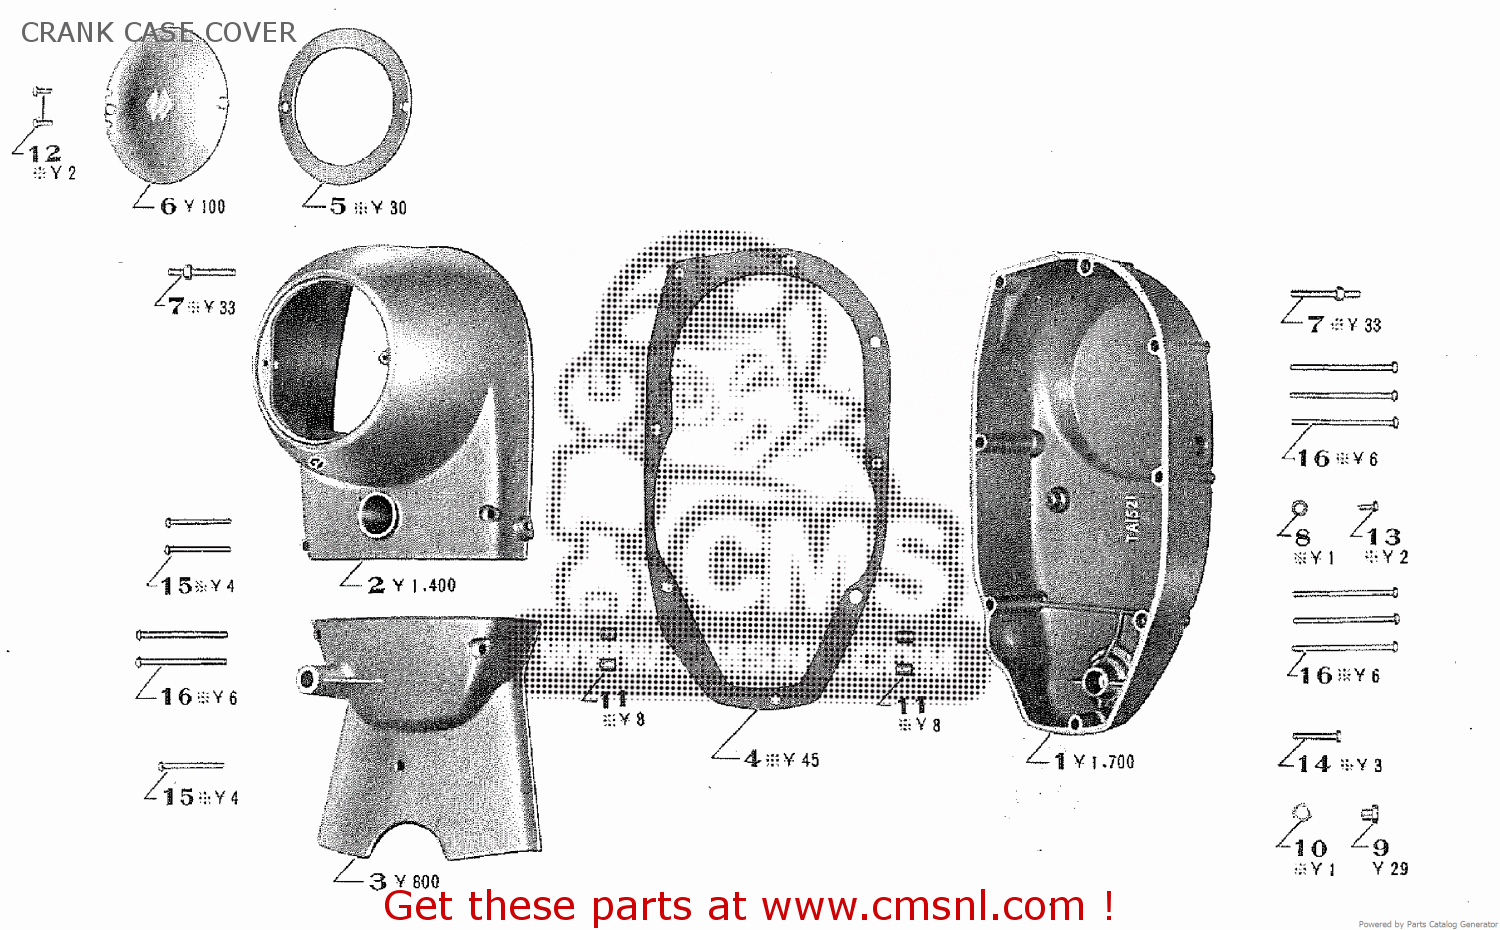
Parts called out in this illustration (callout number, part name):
1	RIGHT COVER
2	DYNAMO COVER
3	SUB CHAIN COVER
4	RIGHT COVER PACKING
5	DYNAMO CAP PACKING
6	DYNAMO CAP
7	SIDE COVER SET STUD
8	OIL LEVEL SCREW PACKING
9	OIL PLUG
10	OIL PLUG PACKING
11	9X12 KNOCK PIN
12	5X10 CROSS SCREW
13	6X10 CROSS SCREW
14	6X35 CROSS SCREW
15	6X45 CROSS SCREW
16	6X65 CROSS SCREW
